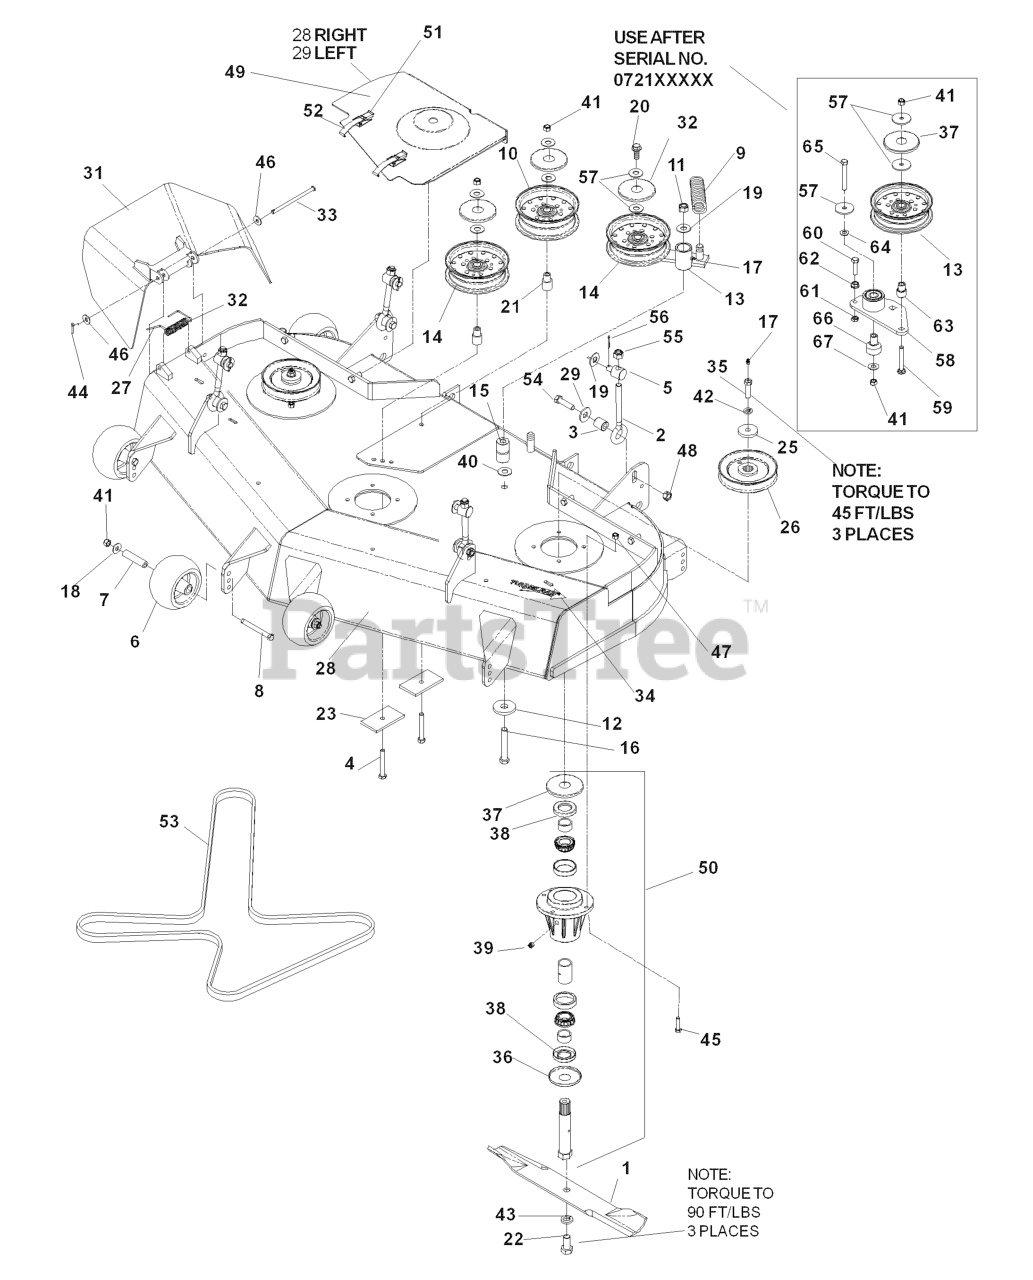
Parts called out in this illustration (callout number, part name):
1	BLADE OEM 18"
4	SCREW 3/8C X 2 3/4 HEX CAP
6	ANTI-SCALP ROLLER
8	HCS 3/8C X 3 1/2
9	DECK SPRING
10	IDLER PULLEY (TALL)
11	NUT 1/2-13 HEX NYLOC ZD
12	WASHER, SUPPORT
14	IDLER PULLEY
15	PIVOT BUSHING
16	HCS 1/2C X 3 1/4
17	ZERK
18	WASHER 3/8 FLAT
19	WASHER 1/2 FLAT
20	4CS 3/8C X 1 SERRATED HEAD
21	IDLER BUSHING
22	HCS 5/8F X 1 1/4
23	SUPPORT PLATE
24	SPRING WASHER - .50
25	SPINDLE WASHER
26	PULLEY, 52
27	CAP-SLEEVE
28	DECK W/DECALS 52" HUS
29	52" BELT SHIELD ASM - RH
30	52" BELT SHIELD ASM - LH
31	DISCHARGE CHUTE 52"
32	SPRING - TORSION
33	PIN-CLEVIS 5/16 DIA X 5.19 ZD
34	DECAL, TUNNEL RAM 8"
35	HCS 7/16-20 GD 8 SPEC
36	BOTTOM DUST CAP
37	TOP DUST CAP
38	SHAFT SEAL
39	PLUG-VENTED
40	WASHER 1/2 X 1.44 HRD ZD
41	NUT 3/8-16 NYLOC
42	WASHER 7/16 LOCK
43	LOCKWASHER 5/8
44	RP_COTTER PIN 1/8 X 3/4
45	HCS 5/16C X 1 1/4
46	WASHER 5/16 FLAT
47	NUT 5/16 NYLOC
48	NUT 7/16C CENTERLOCK
49	DECAL, EURO SEVERING
50	HSG KIT 52/61 RIBBED
51	RIVET, BLIND, 5/32 DIA
52	DRAW LATCH
53	DECK BELT - 52"
54	HCS 7/16 - 14 X 1 3/4
55	NUT 1/2-13 HEX NYLOC ZD
56	PIN COTTER 1/8 X 1 ZD
57	WASHER, 3/8 SPEC
58	ARM-IDLER W/BRG
59	RHSNB 3/8-16 X 2.75
60	HCS 3/8-16 X 1-1/2
61	NUT 3/8-16 HEX JAM
62	NUT 3/8C WHIZ
63	BUSHING, IDLER
64	WASHER 3/8 SAE FLAT
65	HCS 3/8C X 3
66	PIVOT, BEARING
67	WASHER 3/8 FLAT
